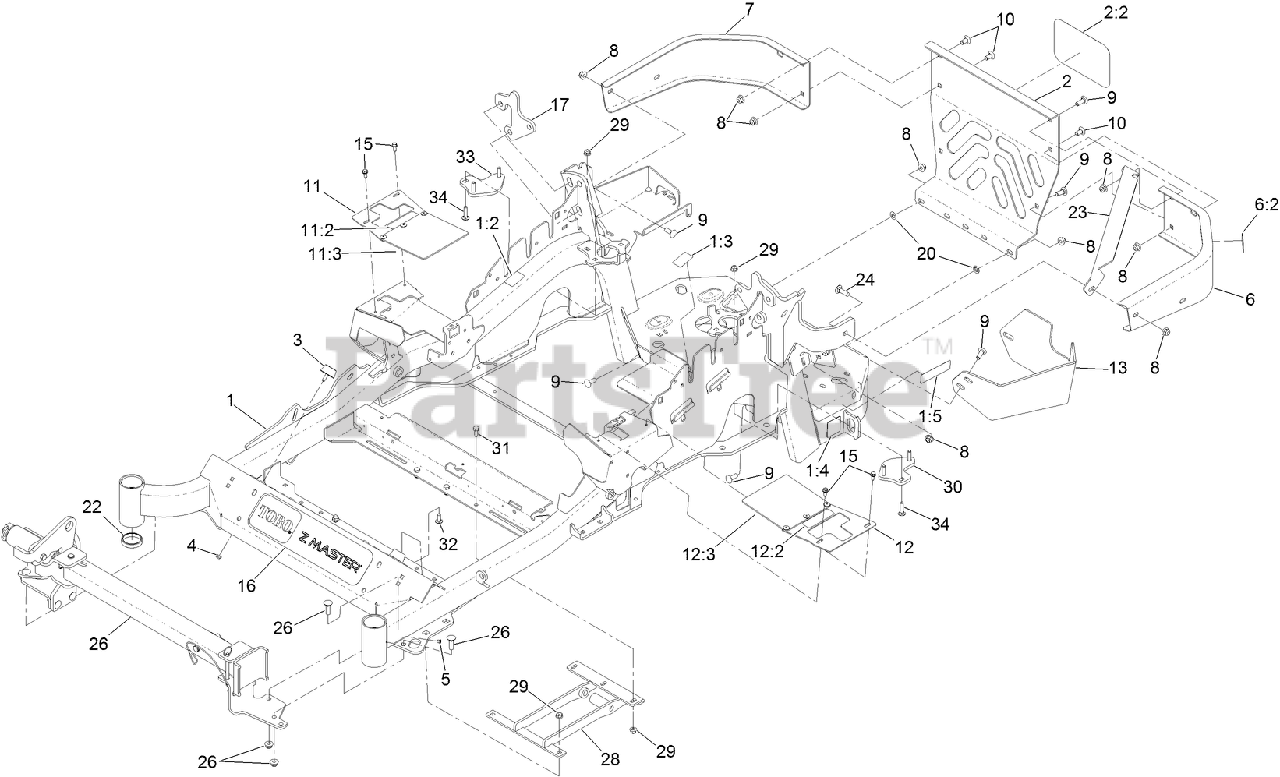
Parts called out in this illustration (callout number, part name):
1	MAINFRAME ASM
1:2	DECAL-DANGER
1:3	DECAL-WARNING
1:4	DECAL-HAZARD, PINCHED FINGER
1:5	DECAL-ARRESTOR, SPARK
2	REAR GUARD ASM
2:2	DECAL
3	BUMPER
4	NUT-HF
6	LH BUMPER ASM
6:2	DECAL-WARNING
7	BUMPER-RH
8	NUT-HF, NI
9	SCREW-CARR
10	SCREW-CARR
11	RH MOTION CONTROL COVER ASM
11:2	DECAL-CONTROL, MOTION
11:3	FLAP-RUBBER
12	LH MOTION CONTROL COVER ASM
12:2	DECAL-CONTROL, MOTION
12:3	FLAP-RUBBER
13	GUARD-MUFFLER
15	SCREW-HWH
17	PLATE-MOUNT, SHOCK
20	NUT-PUSH
22	CUP-BEARING
24	BOLT-CARR
26	Z STAND ASM
28	MOUNT-LOWER
29	NUT-HF, NI
30	LH PLATE ASM (W/STUDS)
31	SCREW-HH
32	SCREW-CARR
33	RH PLATE ASM (W/STUDS)
34	SCREW-CARR
